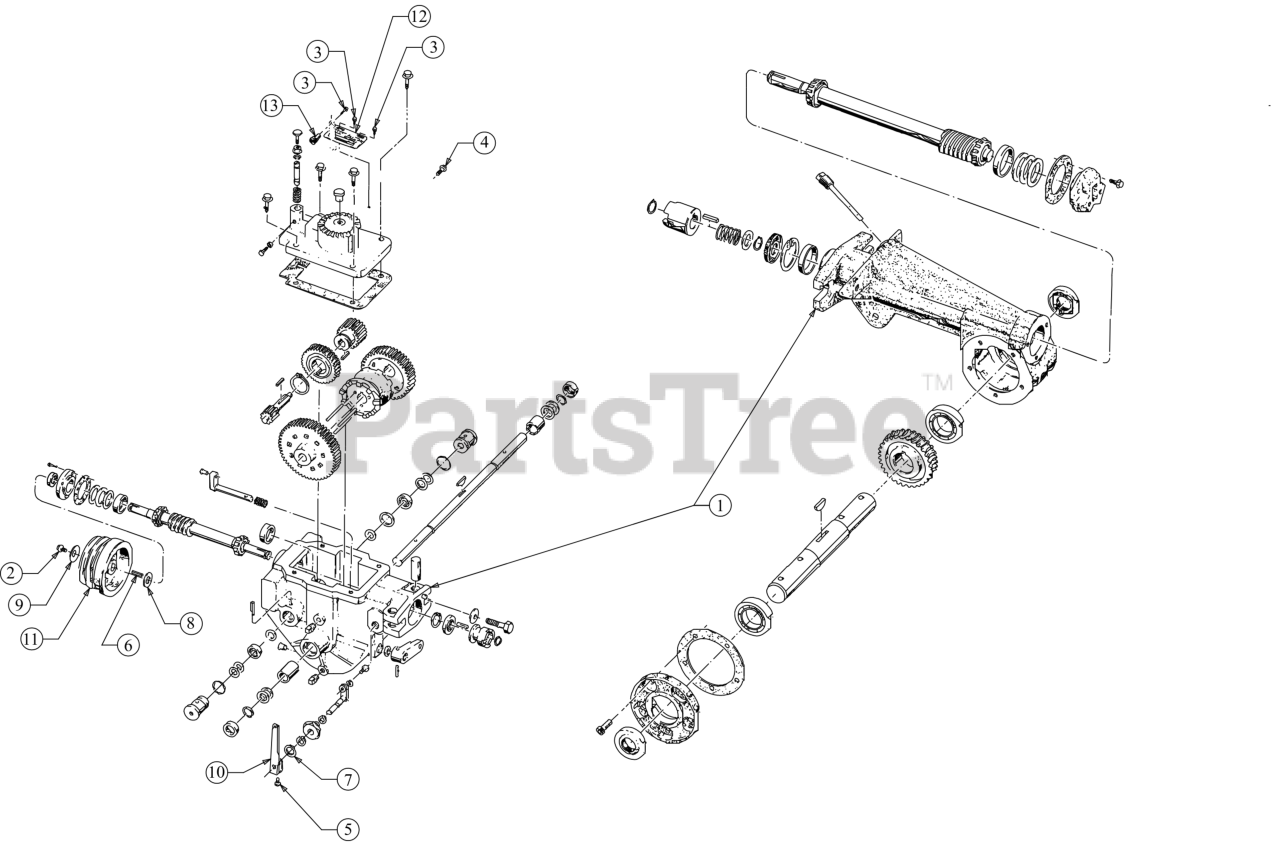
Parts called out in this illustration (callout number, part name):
1	POWER UNIT TRANSMISSION
1	TILLER ATTACHMENT TRANSMISSION
2	HEX SCREW 5/16-24 X .75
3	HEX SCREW #10-32
4	SCREW 5/16-18 x .75 GR5
5	SCREW 1/4-20X.5 GR5
6	SQUARE KEY 3/16 X 1.
7	FLAT WASHER .635 X 1.24 X .181
9	BELLVILLE WASHER .827 X .331 X .098
10	ECCENTRIC LEVER SHAFT
11	TRANSMISSION PULLEY
12	PLATE-TINE ENGAGE
13	KNOB-TAPERED
